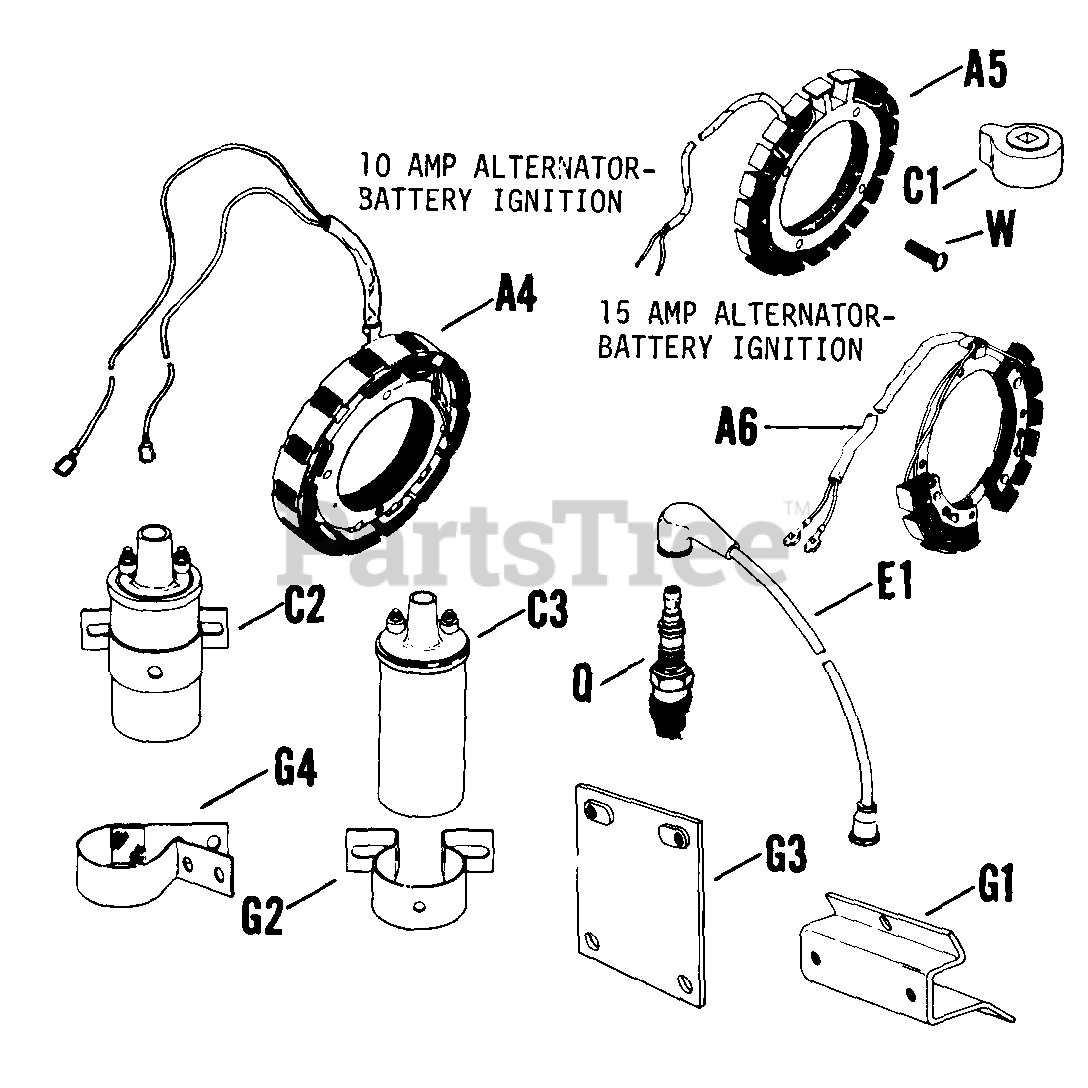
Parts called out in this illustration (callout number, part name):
C2	COIL - USE 231281
E1	KIT, HI-TENSION-(#DSC)
Q	PLUG - DISCONTINUED
